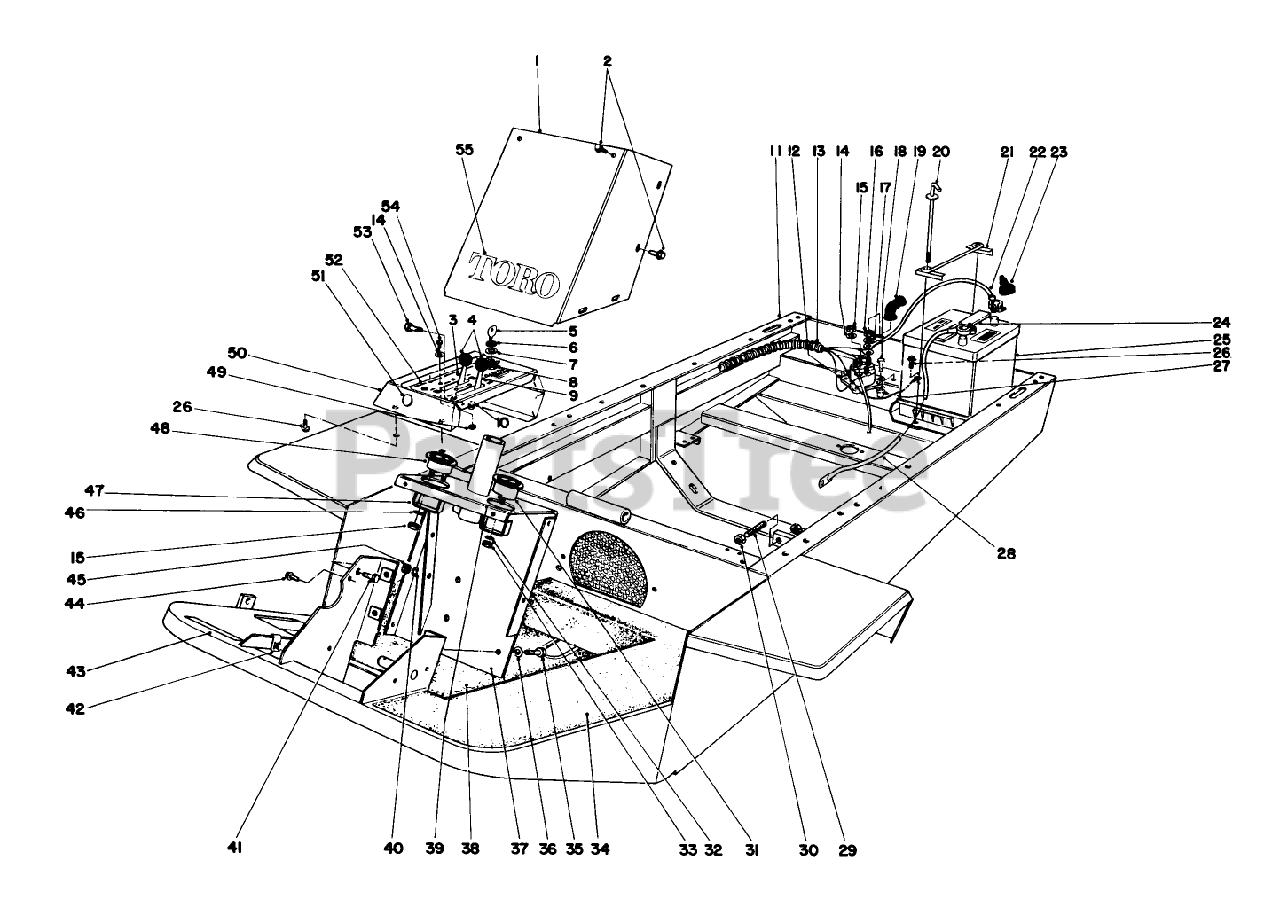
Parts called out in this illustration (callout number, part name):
1	Tower Cover
2	SCREW-HHFTF
3	CHOKE CONTROL
5	Key
6	NUT-HH
7	WASHER-TOOTH, INTERNAL
8	Starter Switch (Incl. Ref. #5-7)
9	THROTTLE CONTROL
10	WASHER-FLAT
11	Frame
12	SOLENOID
13	WIRE HARNESS
14	WASHER-LOCK
15	NUT-HEX
16	NUT-JAM, BRASS
17	WASHER-LOCK
18	SCREW-HH
19	BATTERY BOOT
20	BATTERY BOLT WA B
21	BATTERY HOLD DOWN WA
22	BATT/SOLENOID WIRE
23	BOOT-CABLE, BATTERY
24	PUSH-ON BATTERY CAP
25	Battery
26	SCREW-THD FRM,HWH
27	NUT-INSERT
28	BATTERY GROUND WIRE
29	STOP PIN PP
30	NUT-JAM
31	HOUR METER
32	WASHER-LOCK, INT
33	NUT-HEX
34	NON SKID (TUNNEL)
35	SCREW-HH
36	WASHER-LOCK
37	Steering Post
38	NON-SKID-FLOOR
39	INSTRUCTION DECAL
40	WASHER-LOCK
41	SCREW-HH
42	SPEED NUT
43	DECAL-PEDAL, TRACTION
44	SCREW-HWH
45	NUT-HEX
46	WASHER-FLAT
47	MTG CLAMP F/W GUAGE
48	AMMETER GAUGE ASSY
49	NUT-HEX
50	Instrument Panel
51	Domed Plug
52	Decal-Instrument Panel
53	SCREW-HH
54	10-24 X 5/8 PAN HD MS
55	DECAL
